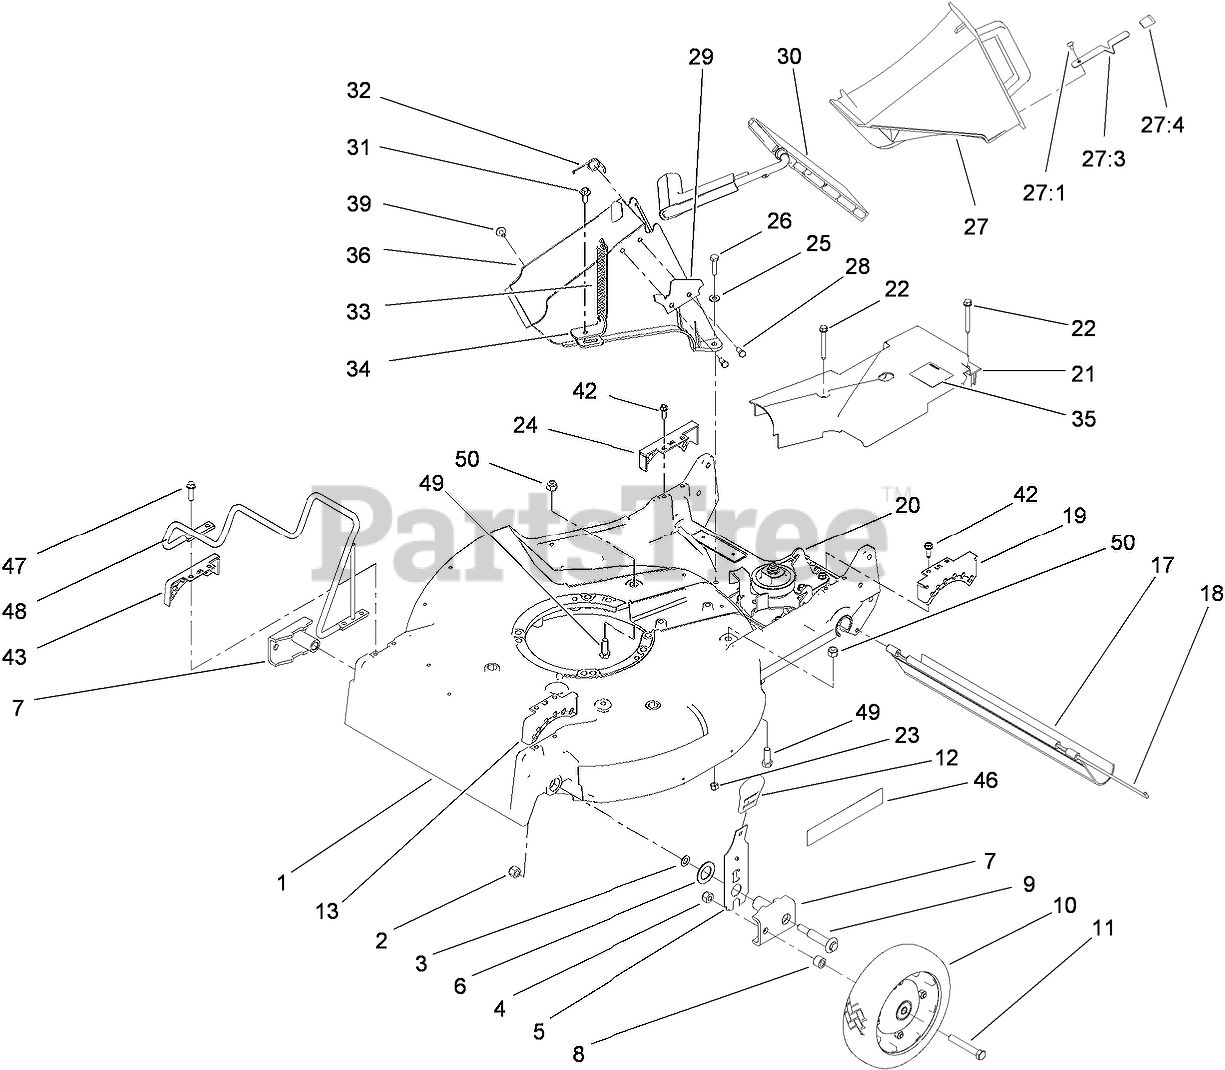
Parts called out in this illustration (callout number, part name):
1	HOUSING
2	NUT-LOCK
3	WASHER
4	NUT-LOCK, CONE
5	FRONT SPRING ARM ASM
6	WASHER-THRUST
7	ARM-PIVOT, FRONT
8	SPACER-WHEEL
9	SCREW-SHOULDER
10	Wheel and Tire ASM
11	SCREW-HH
12	KNOB-HOC
13	QUADRANT-FRONT, LH
17	SHIELD-TRAILING
18	ROD-SHIELD
19	QUADRANT-REAR, LH
20	GEAR CASE ASM
21	COVER-BELT
22	SCREW-HWHTF
23	NUT-LOCK, NI
24	QUADRANT-REAR, RH
25	WASHER-FLAT
26	SCREW-HH
27	DISCHARGE PLUG ASM
27:1	RIVET-HEAD, FLAT
27:3	LATCH-PLUG, DISCHARGE
27:4	GRIP-LATCH
28	SCREW-PLASTITE
29	LATCH-PLATE
30	DISCHARGE DOOR ASM
31	SCREW-HWH
32	RETAINER-DOOR
33	SPRING-DOOR
34	BRACKET-SPRING
35	DECAL-GREASE
36	TUNNEL-DISCHARGE
39	SCREW AND WASHER ASM
42	SCREW-HWHTF
43	QUADRANT-FRONT, RH
47	SCREW-HWHTF
48	GUARD-ENGINE
49	SCREW-HH
50	NUT-LOCK, NI
